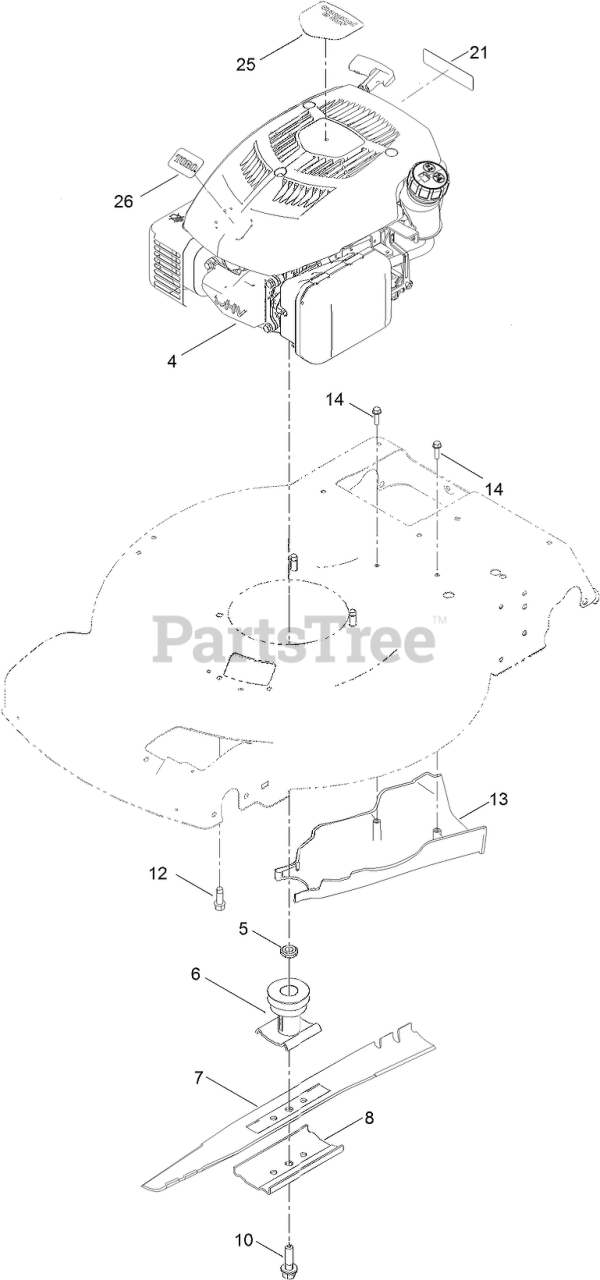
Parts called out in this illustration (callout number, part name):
4	ENGINE-1P65F-2
5	SPACER-DRIVER
6	DRIVER-BLADE
7	BLADE-22 INCH
8	SUPPORT-BLADE
10	BOLT-BLADE
12	SCREW-TAPTITE
13	COVER-BELT, REAR
14	SCREW-HWH
21	DECAL-ARRESTER, SPARK
25	DECAL-ENGINE
